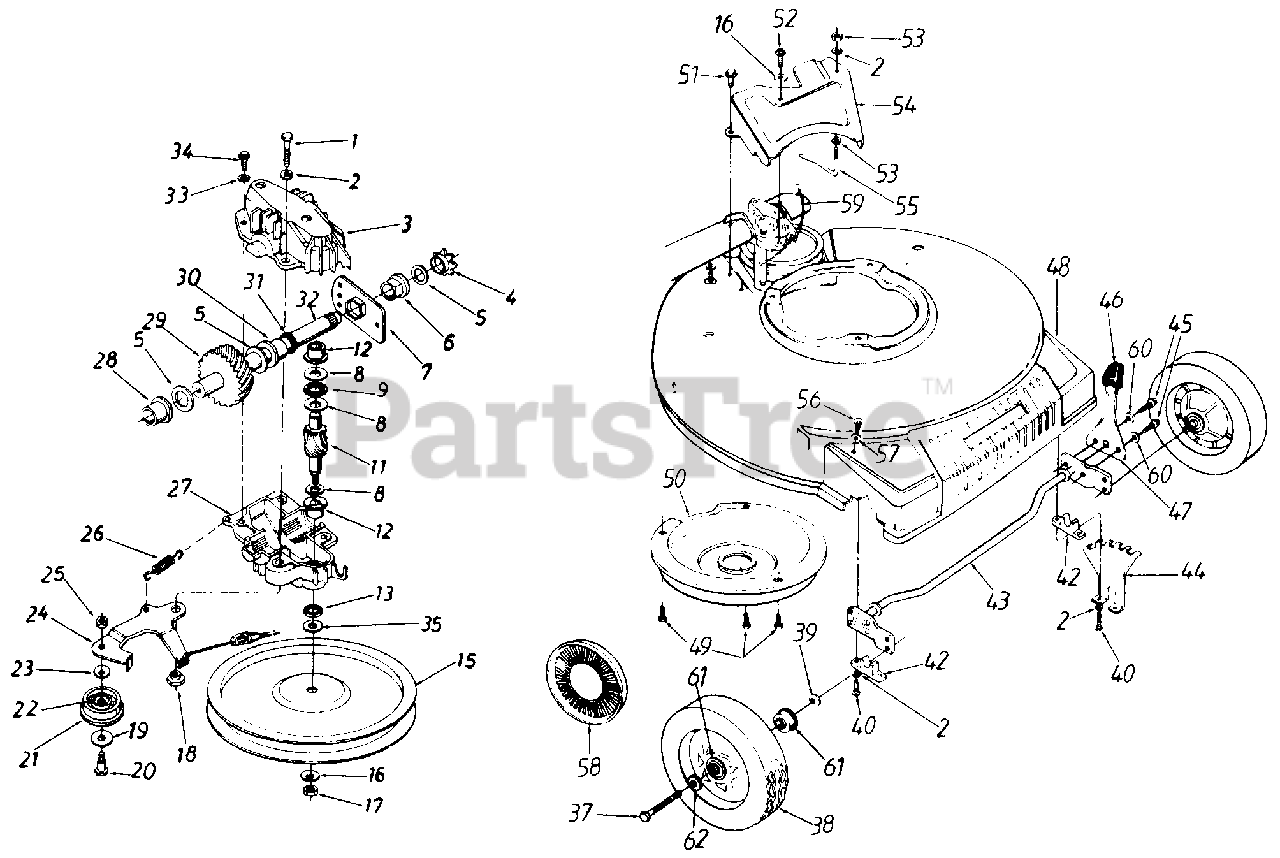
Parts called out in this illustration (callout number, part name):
1	Hex Patch Bolt 1/4-20 x 1.25n
2	L-Wash. 1/4" l.D.
3	Upper Hsg. Half
4	#48 Sprocket 7 T x 1/2 Pitch
5	Fl-Wash. 5/8n l.D. x .030
6	Hex Flange Brg. .631n l.D.
8	Thrust Wash. .382" l.D. x .70" O.D.
9	Thrust Bearing .375" I.D. x .812" O.D.
11	11 Tooth Pinion Shaft
12	Flange Bearing
15	Fl-Pulley 5.06" O.D.
16	Bell-Wash. .265" I.D. x .75"
17	Hex L-Nut 1/4-28 L.H. Thd.
18	Shld. Spacer .375" Dia. x .170
19	Fl-Wash. .890" l.D. x 1.0"
20	Shld. Bolt .375" Dia. x .40"
21	Fl-ldler Plastic 1.50" Dia.
22	Needle Brg. .375" x .31
24	Idler Brk't. Ass'y.
25	Hex Patch L-Nut 1/4-28 Thd.
26	Extension Spring 1.12" Lg.
27	Lower Hsg. Half
28	Flange Bearing .566 Dia.
29	33 Tooth Helical Gear
30	Flange Bearing .629 Dia.
31	Oil Seal .625 Dia.
32	Gear Sprocket Shaft
33	L-Wash. #10 I.D.
34	Hex B-Tap Scr. #10 x .62n
35	Hex Washer .26" x .88"
37	Front Axle Bolt
38	Wheel Ass'y. Comp. 8 x 2"
39	Bell-Wash. 380" l.D. x .88
40	Hex B-Tap Scr. 1/4-20
42	Block Bushing
45	Hex TT-Tap Scr. 1/4-20 x 38"
46	Knob
47	Spring Lever
48	Plastic Front End
49	Hex B-Tap Scr. 1/4" x .38"
52	Hex Wash. Hd. B-Tap Scr. 1/4 x .62"
53	Hex Nut 1/4-20 Thd.
56	Truss B-Tap Scr. 5/16 x 75"
57	Bell-Wash. .345" I.D. x .88"
58	Hub Cap
59	S.P. Cable 44" Lg.
60	External L-Wash. 1/4" l.D.
61	Ball Bearing 1/2" I.D.
62	Wave Wash. 53" l.D. x .78"
